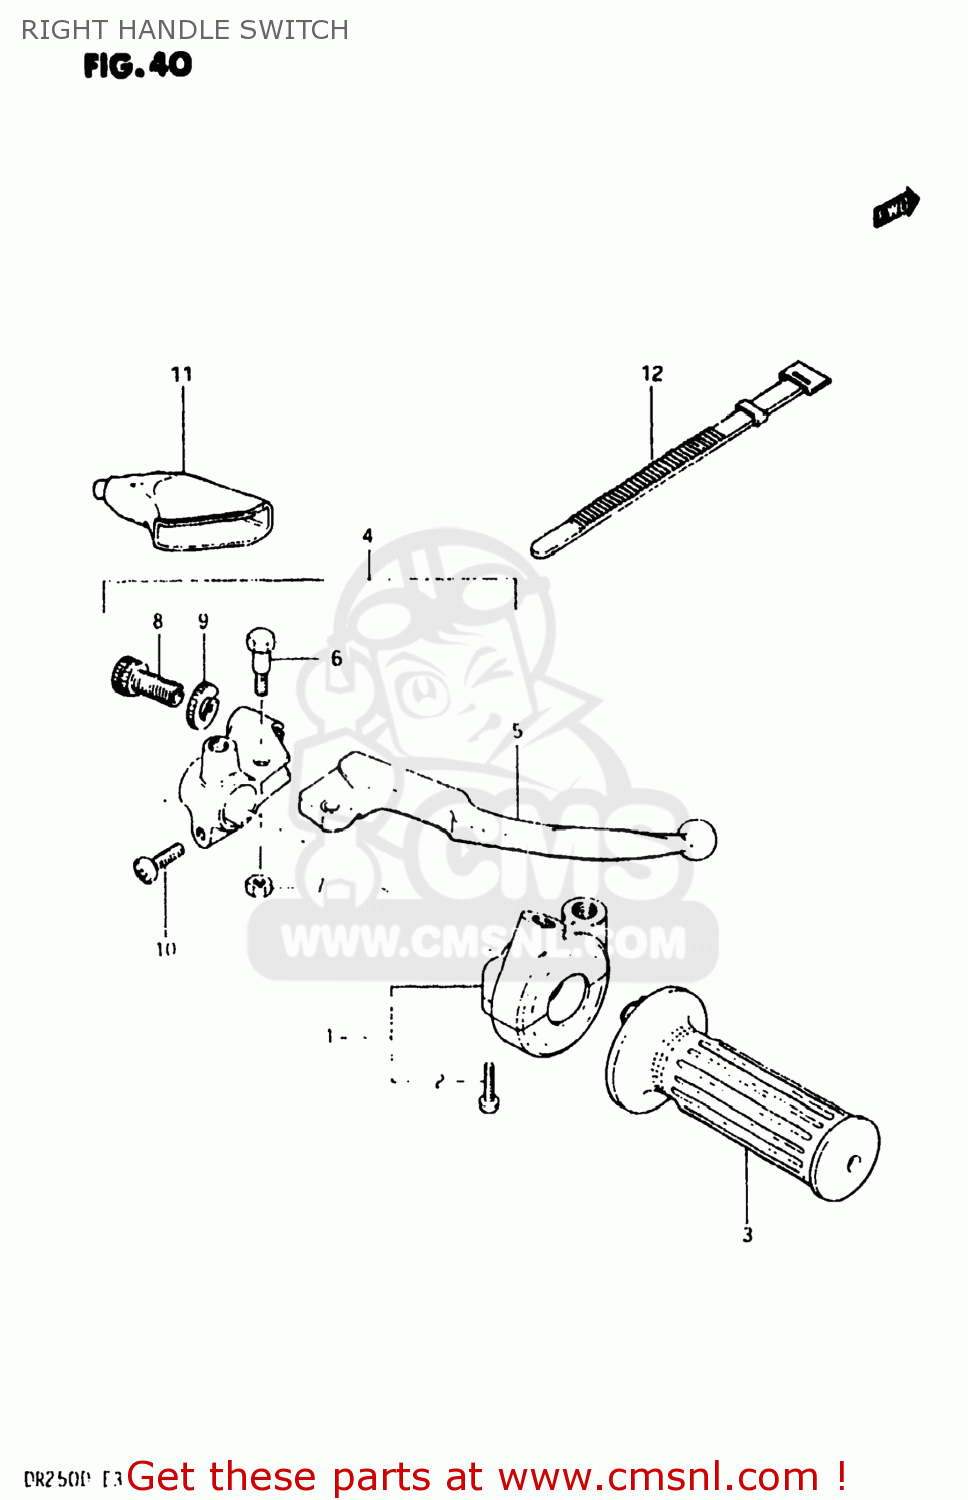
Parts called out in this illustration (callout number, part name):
1	CASE ASSY,THROTTLE
2	SCREW 5X20
3	GRIP,THROTTLE
4	LEVER ASSEMBLY,BRAKE
5	LEVER,BRAKE
6	BOLT,LEVER
7	NUT 6MM
8	ADJUSTER,CABLE
9	NUT,CABLE ADJUSTER
10	SCREW
11	COVER,CLUTCH LEVER
12	CLAMP(L:120)
